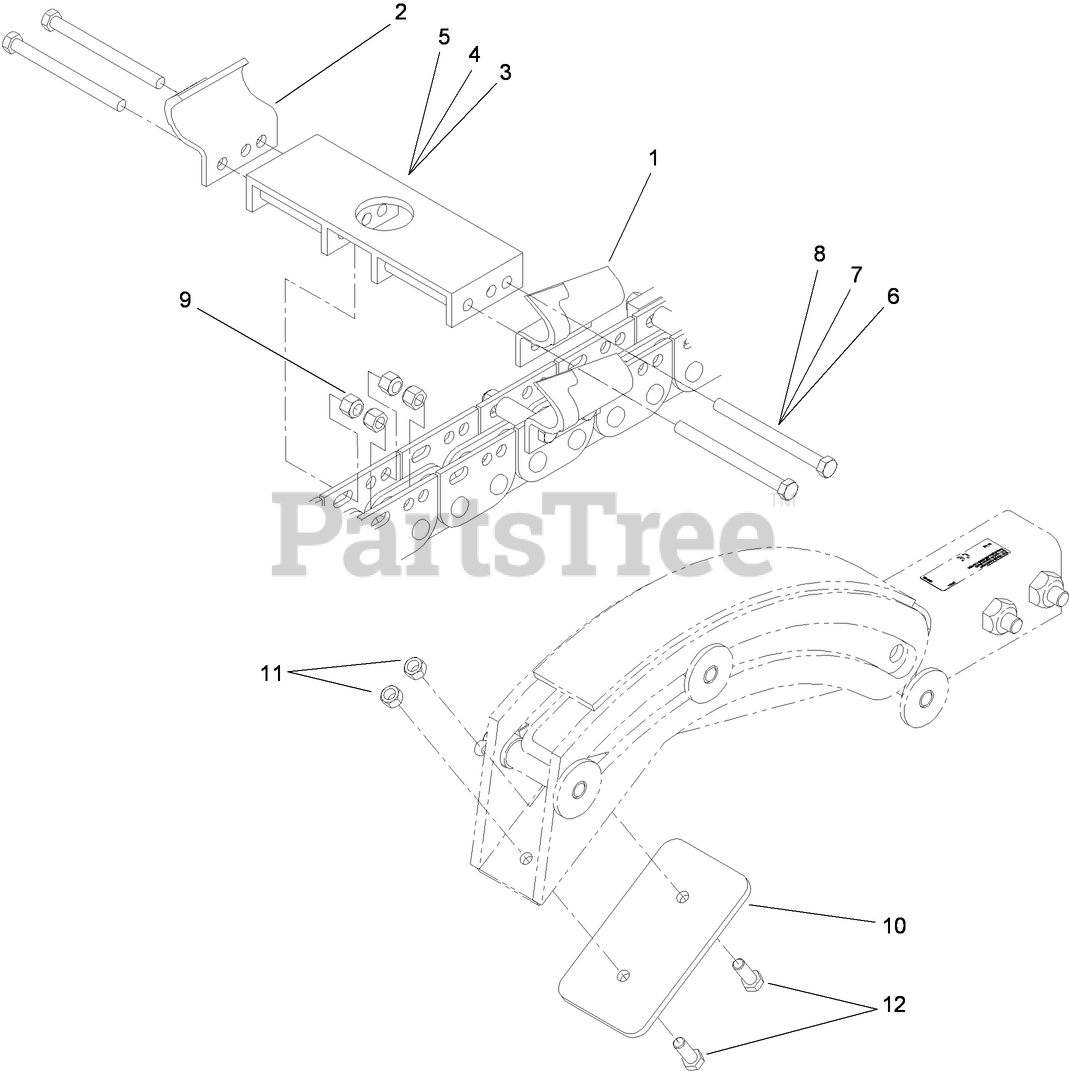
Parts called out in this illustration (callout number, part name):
1	TOOTH-SOIL, LH
2	TOOTH-SOIL, RH
3	ADAPTER-8 Inch
4	ADAPTER-10 Inch
5	ADAPTER-12 Inch
6	SCREW-HH (FOR 8-INCH ADAPTER)
7	SCREW-HH (FOR 10-INCH ADAPTER)
8	SCREW-HH (FOR 12-INCH ADAPTER)
9	NUT-LOCK
10	PLATE-DEFLECTOR, 12 INCH
11	NUT-LOCK, SIDE
12	SCREW-HH
